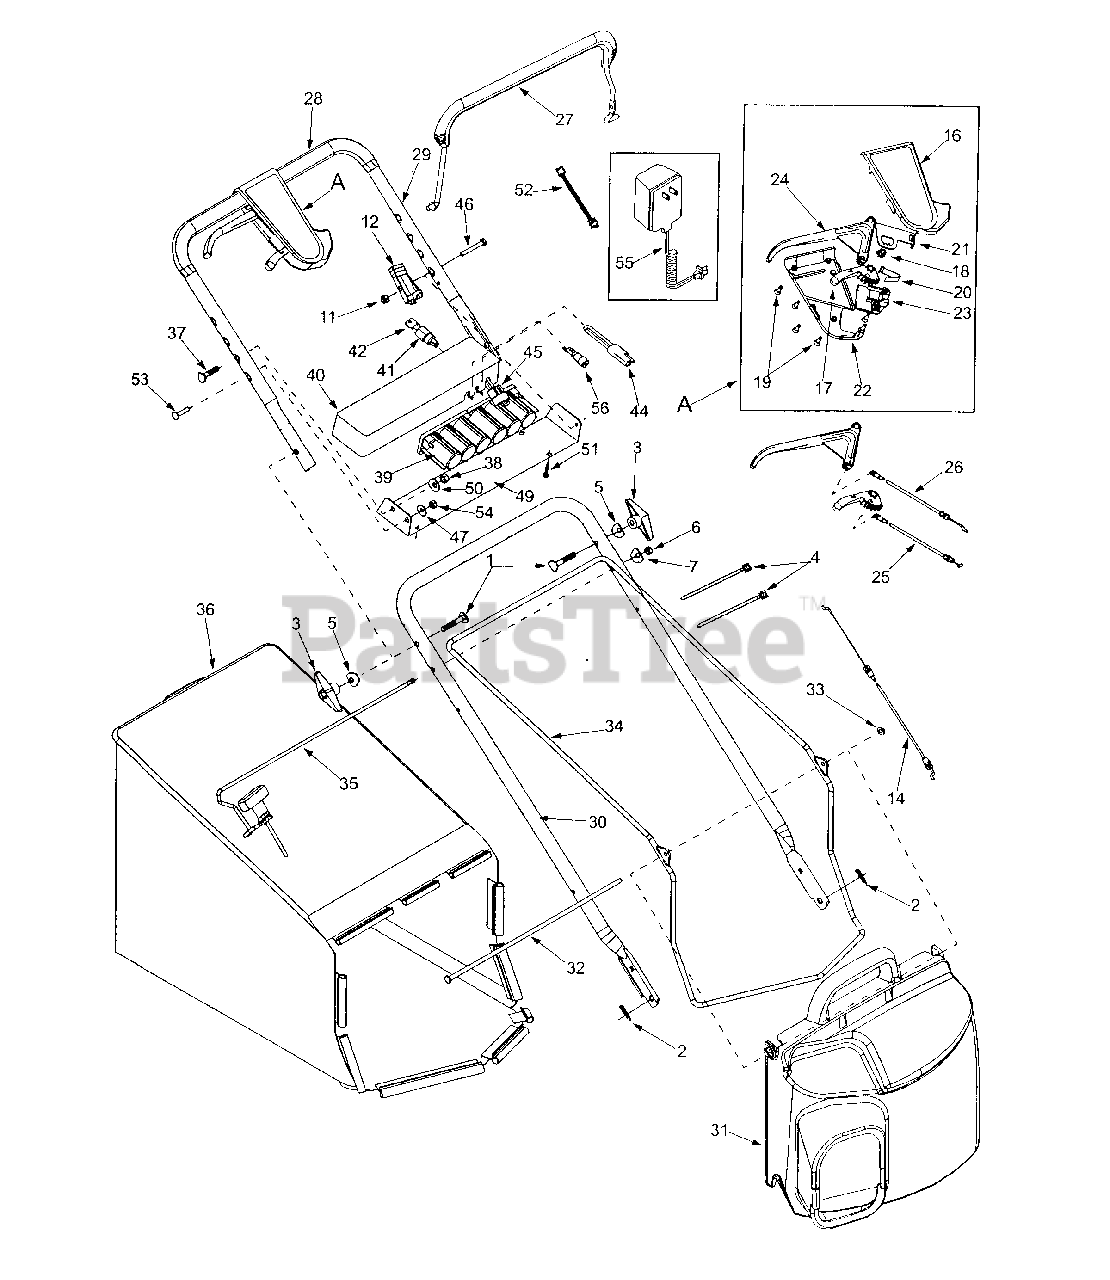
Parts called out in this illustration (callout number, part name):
1	Carriage Bolt 5/16-18 x 2.0
2	Cotter Pin .072 x 1.12 Lg.
3	Knob Assembly 5/16-18
4	Cable Tie
5	Saddle Washer .320 ID x .830 OD
6	Handle Knob 1/4-20
7	Saddle Washer
11	Lock Nut 1/4-20
12	Control Cable Housing
14	Control Cable 44"
16	Upper Control Housing
17	6 Speed Shift Lever
18	Gear Insert
19	C Sunk Tap Screw #10
20	Shift Lever Spring
21	6 Speed Rack Cable Brkt.
22	Lower Control Housing
23	Cable Mounting Cap
24	Control Lever
25	6 Speed Cable
26	Drive Cable 52"
27	Control Handle
28	Foam Grip
31	Grass Bag Cover
36	Grass Bag
37	Carriage Bolt 5/16-18 x 1"
38	Hex Nut 5/16-18
39	Battery Pack
41	Ignition Switch
42	Ignition Key
44	Plug
45	Wire Harness
46	Hex Bolt 1/4-20 x 1.3"
47	Bell Washer 1/4" ID
51	Tap Screw 1"
52	Harness Extension
53	Screw 1/4-20 x 1.25
54	Hex Nut 1/4-20
55	Battery Charger
56	Fuse Holder
